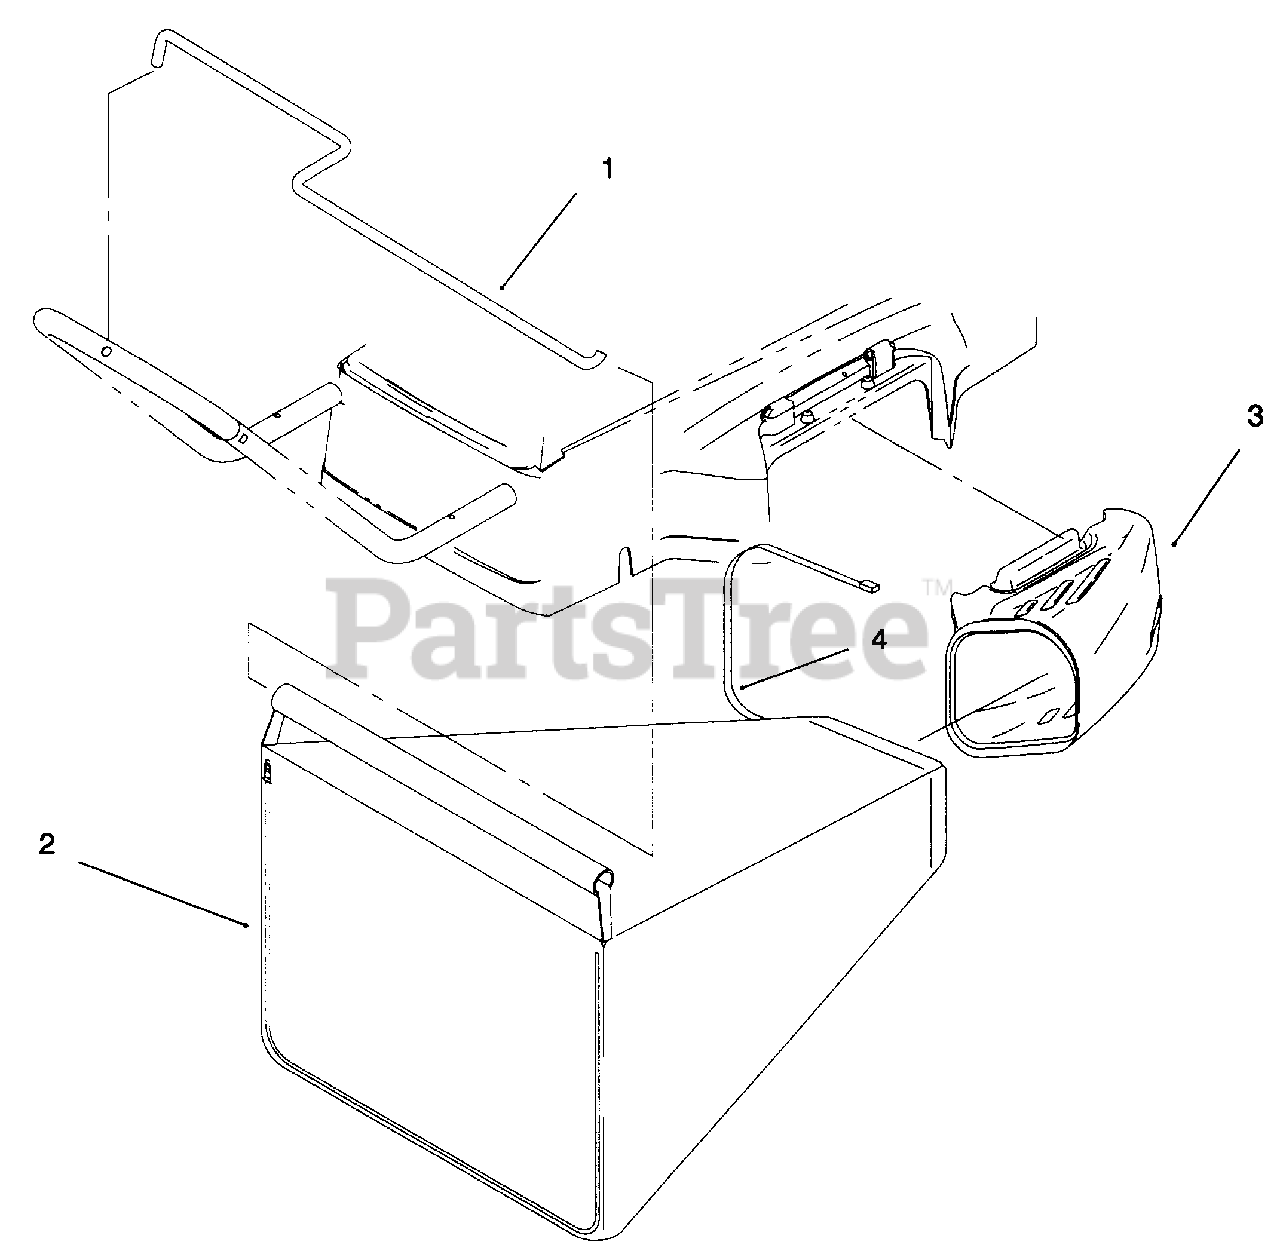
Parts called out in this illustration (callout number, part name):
2	Bag Assembly
3	Chute-Bag
4	Wire Tie
